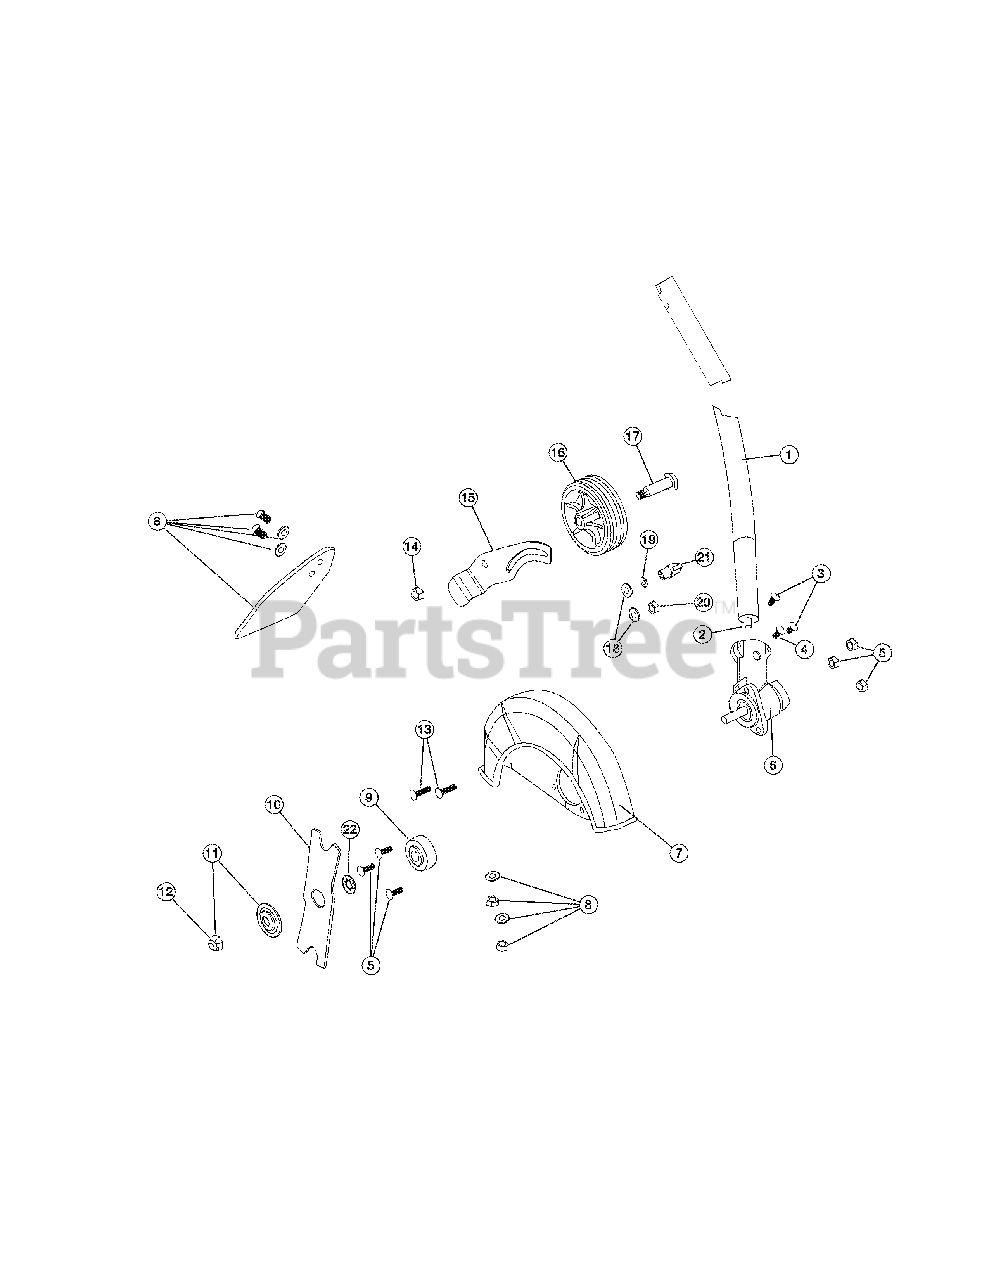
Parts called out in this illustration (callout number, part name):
1	Boom Assembly
2	Drive Shaft
3	Boom Mounting Hardware
4	Anti-Rotation Screw
5	Guard Mounting Hardware
6	Gearbox Assembly
7	Blade Guard
8	Deflector w/Hardware
9	Spacer
10	Blade
11	Blade Clamp Washer
12	Blade Retainer Nut
13	Wheel Bracket Mounting Bolt
14	Nut
15	Edger Guide
17	Shoulder Bolt
19	Washer
20	Nut
21	Edger Guide Knob
